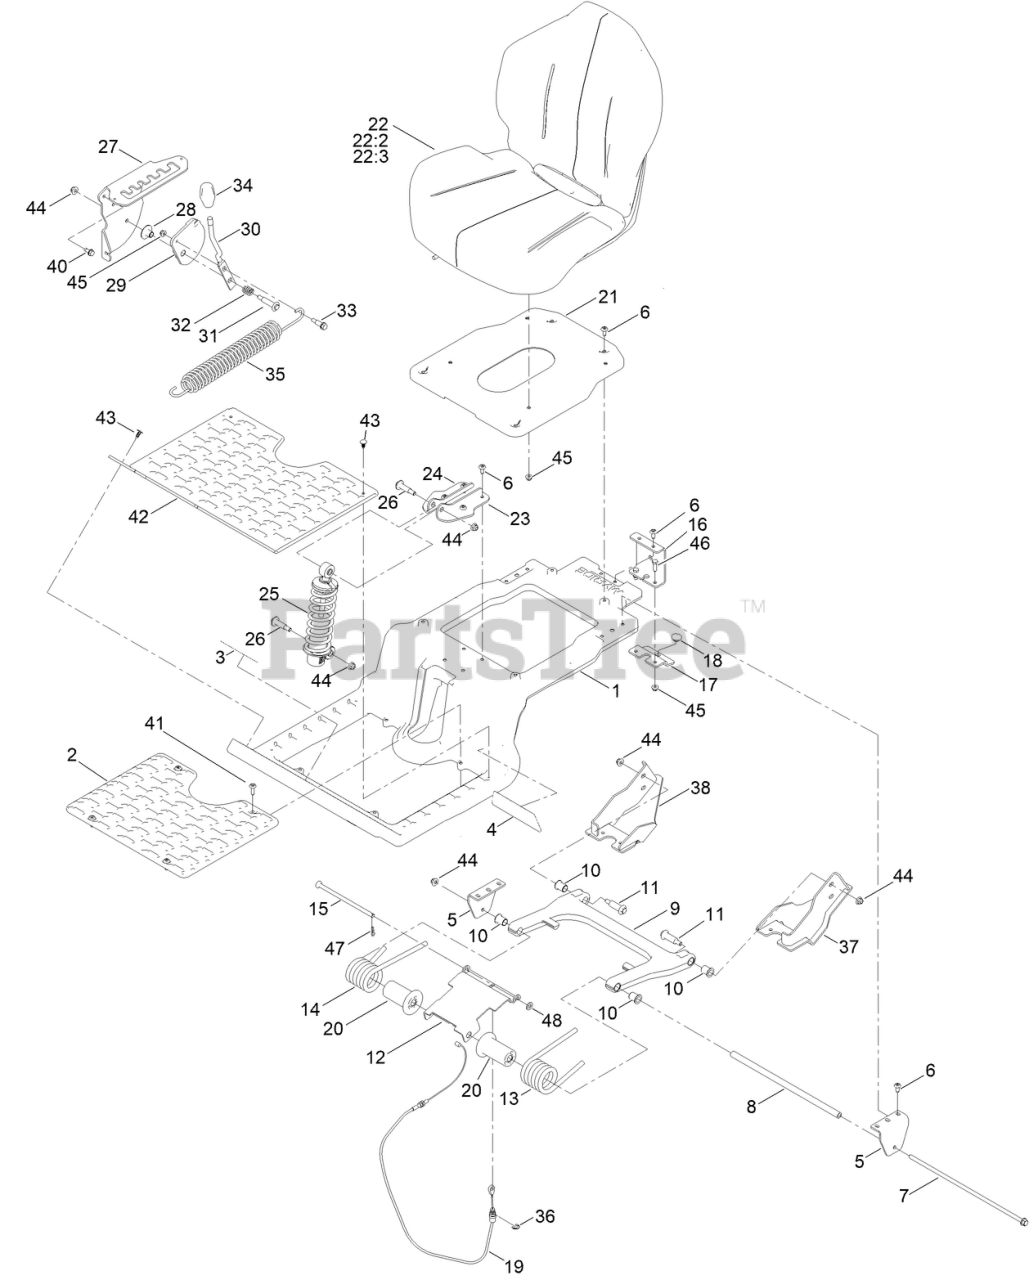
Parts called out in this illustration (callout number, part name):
1	PLATFORM, MYRIDE
2	PLATFORM, MYRIDE
3	DECAL - MYRIDE
4	DECAL - MYRIDE
5	BRACKET-MOUNT, SWING ARM
7	SCREW-HHF
8	TUBE-SPACER
9	ARM-SWING
10	BUSHING-FLANGE
11	BOLT-SHOULDER
12	PLATE-ADJUSTER
13	SPRING-TORSION, LH
14	SPRING-TORSION, RH
15	ROD-ADJUSTMENT
16	BRACKET-CABLE
17	BRACKET LOWER
18	BUMPER-SEAT
19	CABLE-ADJUSTMENT, MYRIDE
20	RETAINER-SPRING
21	PAN-SEAT [BLACK]
22	SEAT ASM - MILSCO CS180D
22:2	KIT-ADJUSTER
22:3	SWITCH-BAIL
23	BRACKET-SHOCK MOUNT, UPPER (LH)
24	BRACKET-SHOCK MOUNT, UPPER (RH)
25	SHOCK/SPRING ASM
26	BOLT-SHOULDER
27	BRACKET-MR GATE
28	BUSHING - FLANGE
29	PULLEY-CAM
30	LEVER-ADJUSTMENT, THREADED
31	BOLT-SHOULDER
32	SPRING-COMPRESSION
33	BOLT-SHOULDER, HHF
34	KNOB-MR
35	SPRING-EXTENSION
36	RING-RETAINING, EXTERNAL
37	MOUNT-MR SWING ARM, LH
38	MOUNT-MR SWING ARM, RH
40	SCREW-HWHTF
41	SCREW-SPCL
42	FLOOR MAT
43	PLUG-PLASTIC
44	NUT-HF, NI
45	NUT-HF
46	SCREW-HH
47	PIN-HAIR
48	WASHER-FLAT
